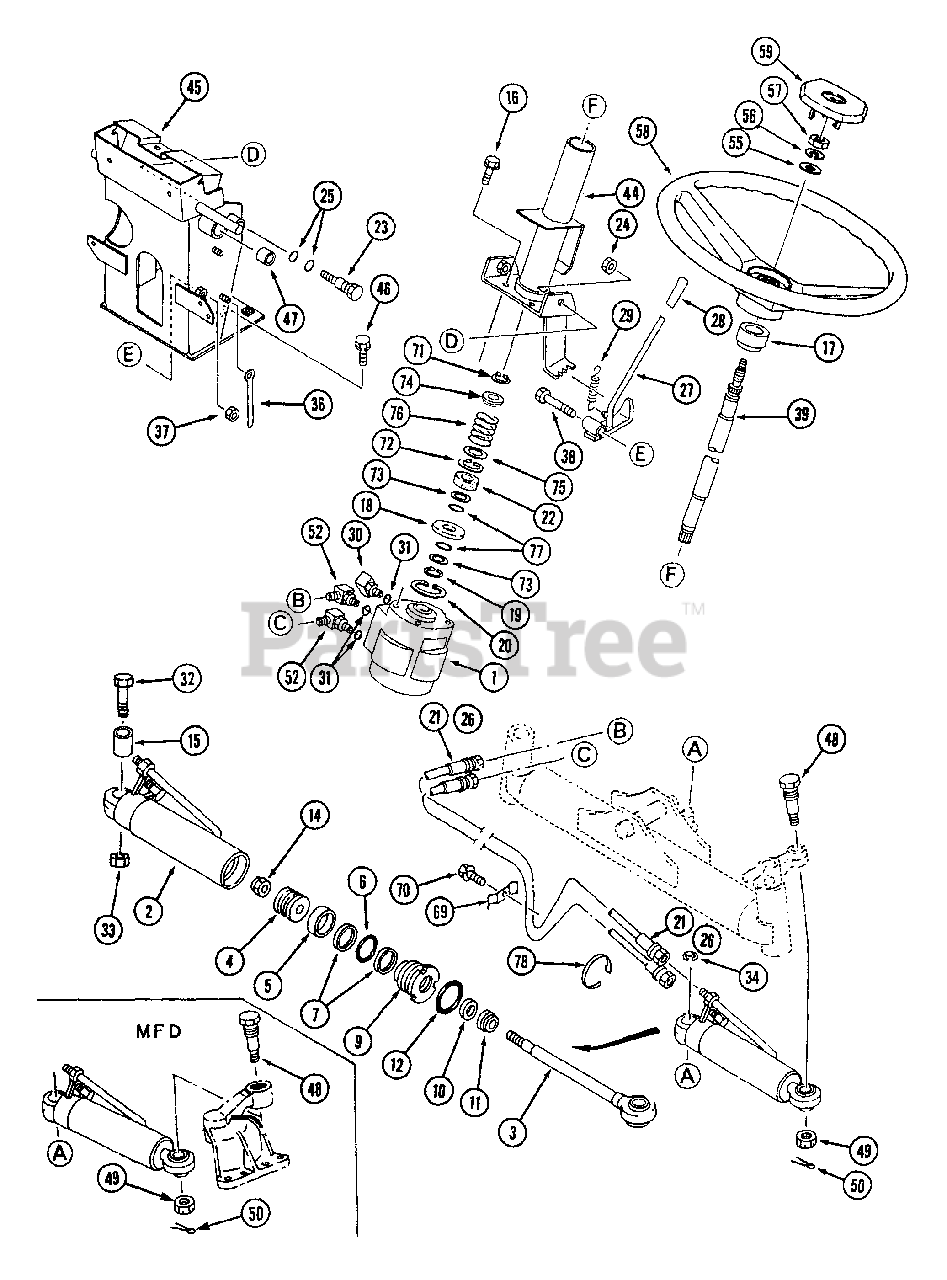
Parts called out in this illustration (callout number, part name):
1	Steering Unit
3	Rod, Cylinder
17	Bushing, Column
21	Hose
32	Bolt
33	Nut
39	Shaft, Steering
45	Bracket, Column
52	Elbow w/O-Ring
58	Steering Wheel
